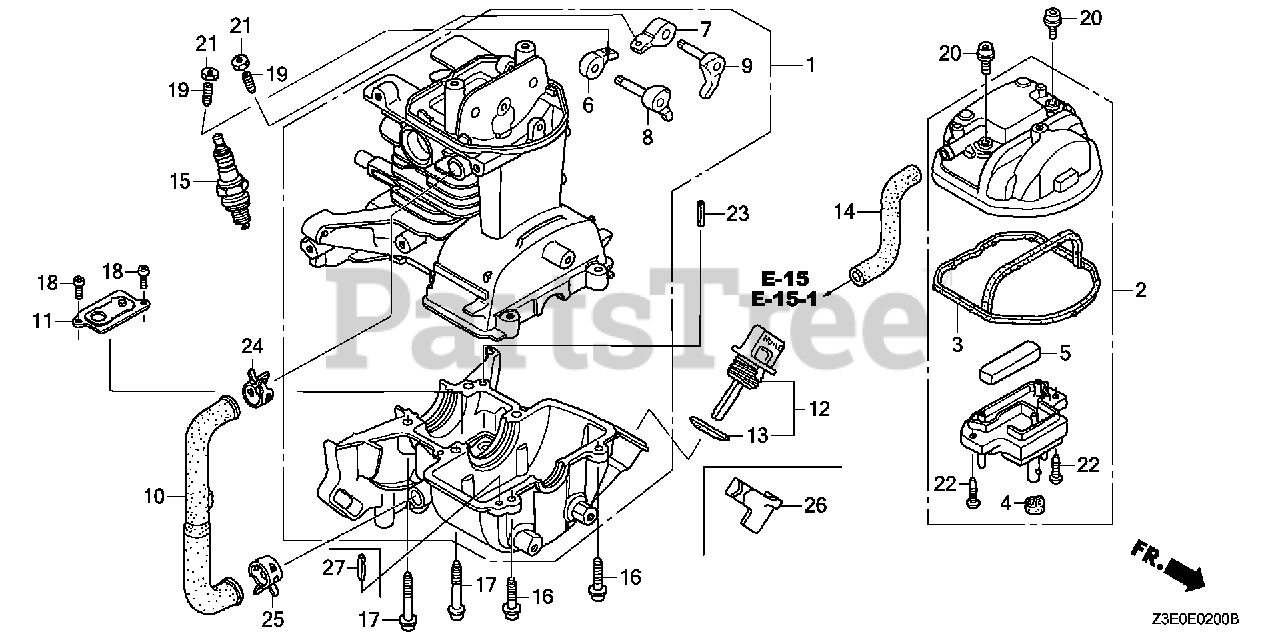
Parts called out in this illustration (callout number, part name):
1	CRANKCASE SET
2	COVER, CYLINDER HEAD
3	SEAL, HEAD COVER
4	GROMMET, HEAD COVER
5	FILTER, BREATHER
6	ARM, IN. VALVE ROCKER
7	ARM, EX. VALVE ROCKER
8	LIFTER, IN. VALVE
9	LIFTER, EX. VALVE
11	PLATE ASSY., OIL OUTLET VALVE
12	CAP ASSY., OIL FILLER
13	GASKET, OIL FILLER CAP
14	TUBE, BREATHER
15	SPARK PLUG (CMR4H) (NGK)
15	SPARK PLUG (CMR5H) (NGK)
15	SPARK PLUG (CMR6H) (NGK)
16	BOLT, SOCKET (5X20)
17	BOLT, SOCKET (5X32)
18	SCREW, PAN (4X8)
19	SCREW, TAPPET ADJUSTING
20	BOLT, SOCKET (5X12)
21	NUT, TAPPET ADJUSTING
22	SCREW, TAPPING (4X12)
23	PIN, SPRING (4X10)
24	CLAMP, TUBE (D12)
25	CLAMP, TUBE (D13)
27	PIN, SPRING (4X10)
